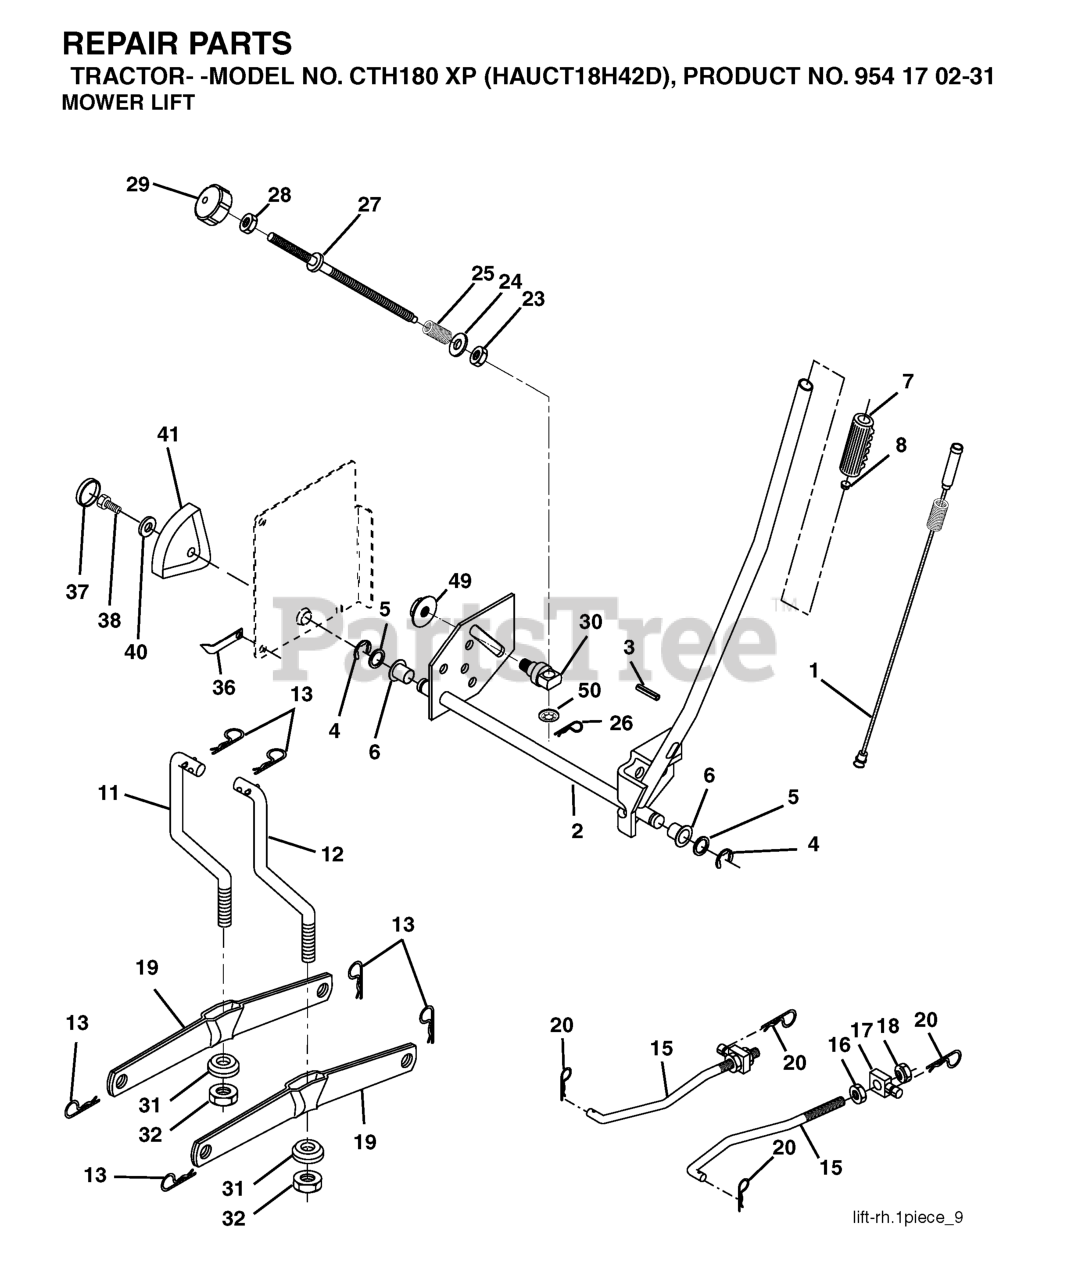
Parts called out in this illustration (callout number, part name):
1	WIRE.ASM.INNER.SP
2	SHAFT.ASM.LIFT.RH.INF
3	PIN.GROOVE.5/16
4	RETAINING RING LT
6	BEARING.NYLON
7	GRIP HANDLE
8	PLUNGER BUT KIT
11	LINK
12	LINK
13	RETAINER-SPRNG RB
15	LINK.SUSPENSION.FRONT
16	NUT.HEX.JAM.1/2-13
18	NUT.LK.W/WSH.1/2.
19	ARM.REAR.SUSPENSION
20	SPRING RETAINER
25	SPRING.COMP.INF.H
26	RETAINER CLIP
27	ROD.LIFT.ADJUSTABLE
28	NUT
29	KNOB INF 3/8-16
31	BEARING.PIVOT.LIFT
32	NUT CROWNLOCK 3/8-24
36	POINTER, HEIGHT INDICATOR(2 2)
38	SCREW 5/16-18X1
41	HEIGHT INDICATOR
49	NUT
50	NUT PUSH M
